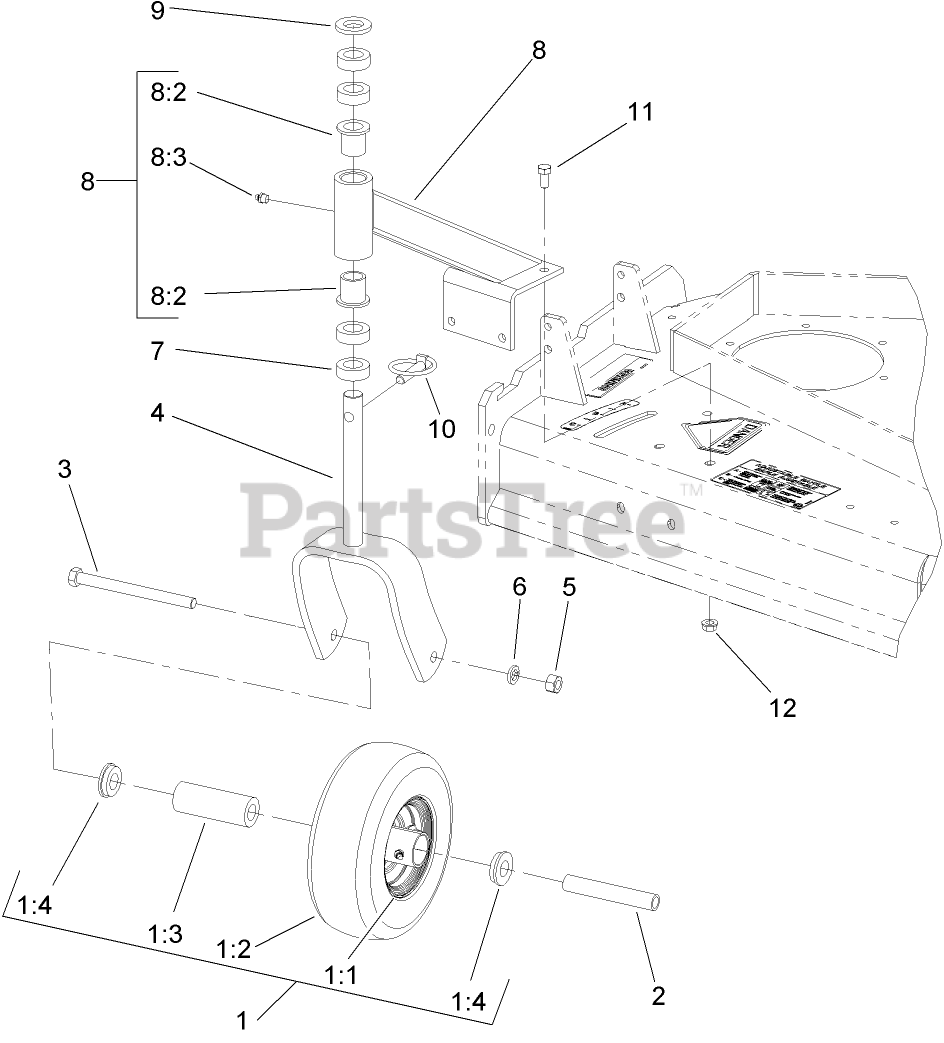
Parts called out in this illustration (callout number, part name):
1	WHEEL AND TIRE ASM
1:1	Rim
1:3	BEARING
1:4	BUSHING
2	SPACER
3	SCREW-HH
4	FORK
5	NUT-HH
6	WASHER-LOCK
7	SPACER-CASTER
8	SUPPORT ASM
8:2	BEARING-FLANGED
8:3	FITTING-GREASE
9	WASHER-FLAT
11	SCREW-HH
12	NUT-HHF, WHIZ
